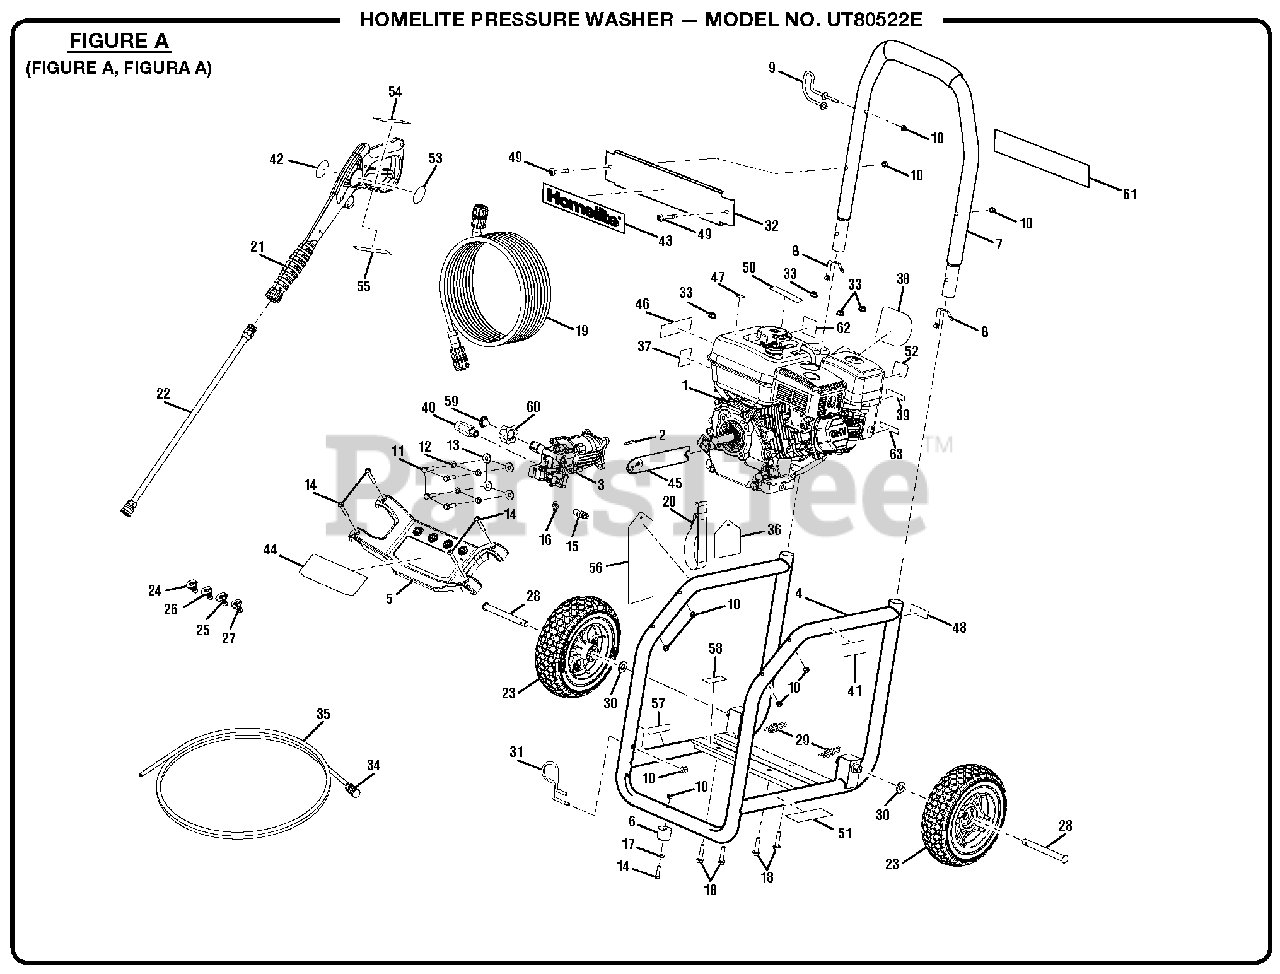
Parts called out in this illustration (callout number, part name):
1	Engine (180cc Horizontal Shaft, EPA)
2	Output Shaft Key (3/16 x 40 mm)
4	Main Frame
5	Nozzle Holder
6	Rubber Foot
7	Handle Assembly
8	Lock Button w/Spring Clip
9	Wand Holder (Upper)
10	Lock Nut (1/4-20)
11	Bolt (5/16-24 x 27 mm, Hex Hd.)
12	Lock Washer (5/16 in.)
13	Washer (5/16 in.)
14	Screw (1/4-20 x 2.0 in., Torx)
15	Thermal Release Valve
16	Detergent Suction Kit
17	Washer (1/4 in.)
18	Bolt (M8 x 36 mm, Hex Flange Hd.)
20	Hook and Loop Strap
21	Trigger Handle
22	Extension Wand
23	Wheel Assembly (10 in. x 3 in.)
24	Nozzle, 0deg
25	Nozzle 40deg
26	Nozzle 25deg
27	Soap Nozzle
29	Hitch Pin
30	Washer (1/2 in.)
31	Wand Holder (Lower)
32	Front Panel
33	Lock Nut (M8 x 1.25)
35	Chemical Siphon Tube
36	Nozzle Instructions Hangtag
37	Engine Label (On-Off)
38	Recoil Label
39	Choke Label
40	Outlet Tube
41	Hot Surface Label
42	Trigger Handle Logo Label
43	Homelite Label
44	Performance Label
45	Add Oil Label
46	Danger Label
47	E85 Label
48	Homelite Inquiries Label
49	Screw (1/4-20 x 43 mm, Torx T-30)
50	No Oil to Gas Label
51	Combustion Label
52	Choke/Fuel Valve Label
53	Trigger Handle Warning Label (French and Spanish)
54	Warning Label
55	Wand Label (Max Rating)
56	Danger Hangtag
57	Lubricant Label
58	Dip Stick Label
59	Filter Screen
60	Inlet Tube
61	Quick Start Label
62	Squeeze Trigger Label
63	Fuel On/Off Label
